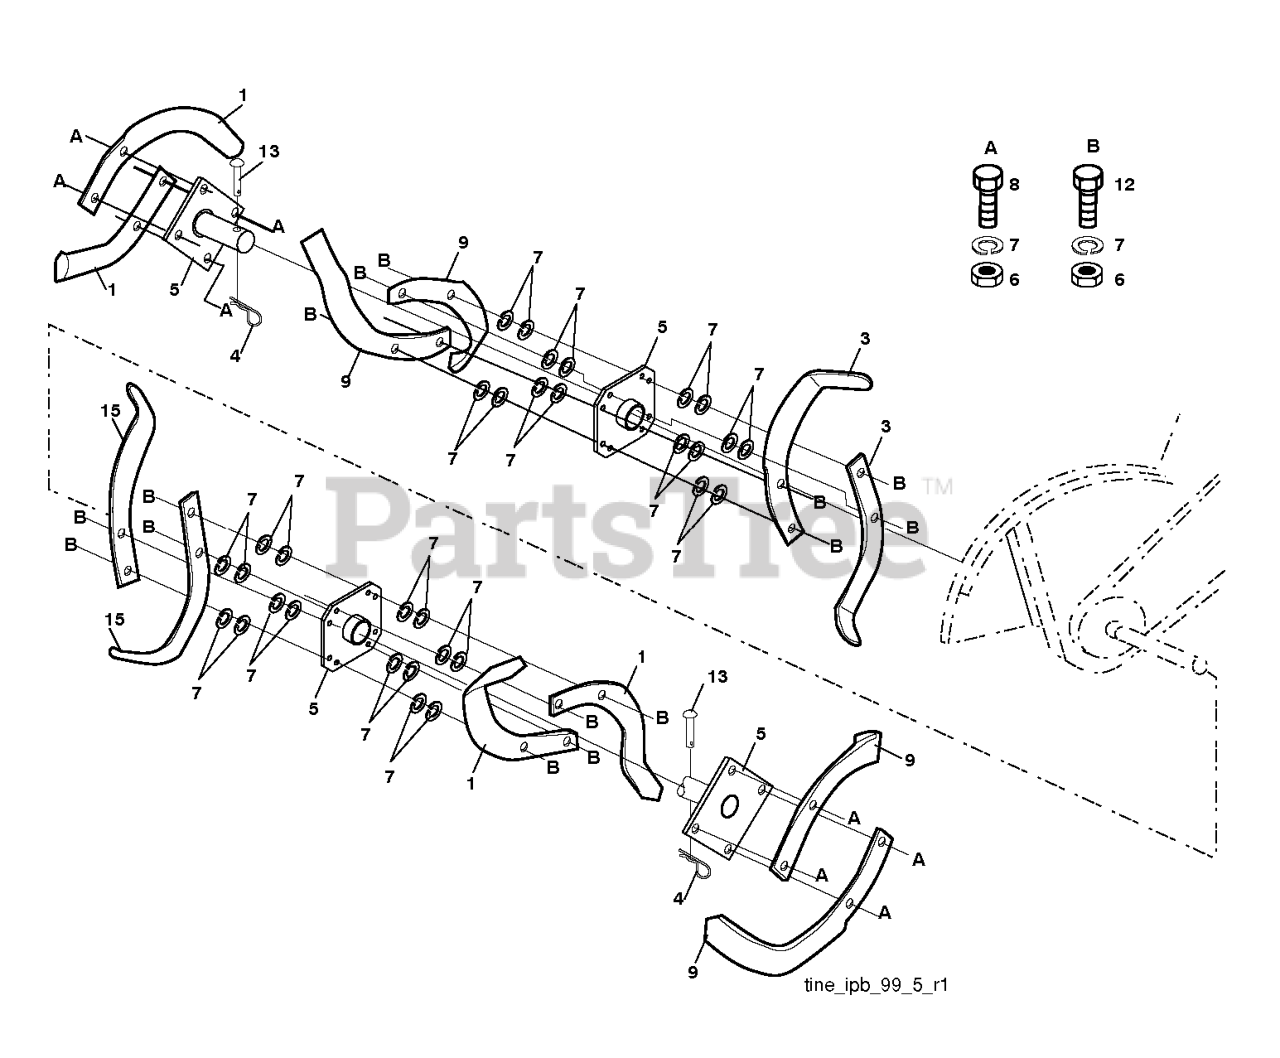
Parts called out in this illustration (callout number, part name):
1	TINE, LH 14"
3	TINE.LH.14".CRT
4	SPRING RETAINER
5	TINE.HUB.ASM.W/SHEILD
6	NUT
7	WASHER, LOCK 3/8
8	BOLT.HEX.001X20.37-24X1.ZINC
9	TINE, RH 14"
12	BOLT.3/8-24X1-1/2
15	TINE.RH.14".CRT
